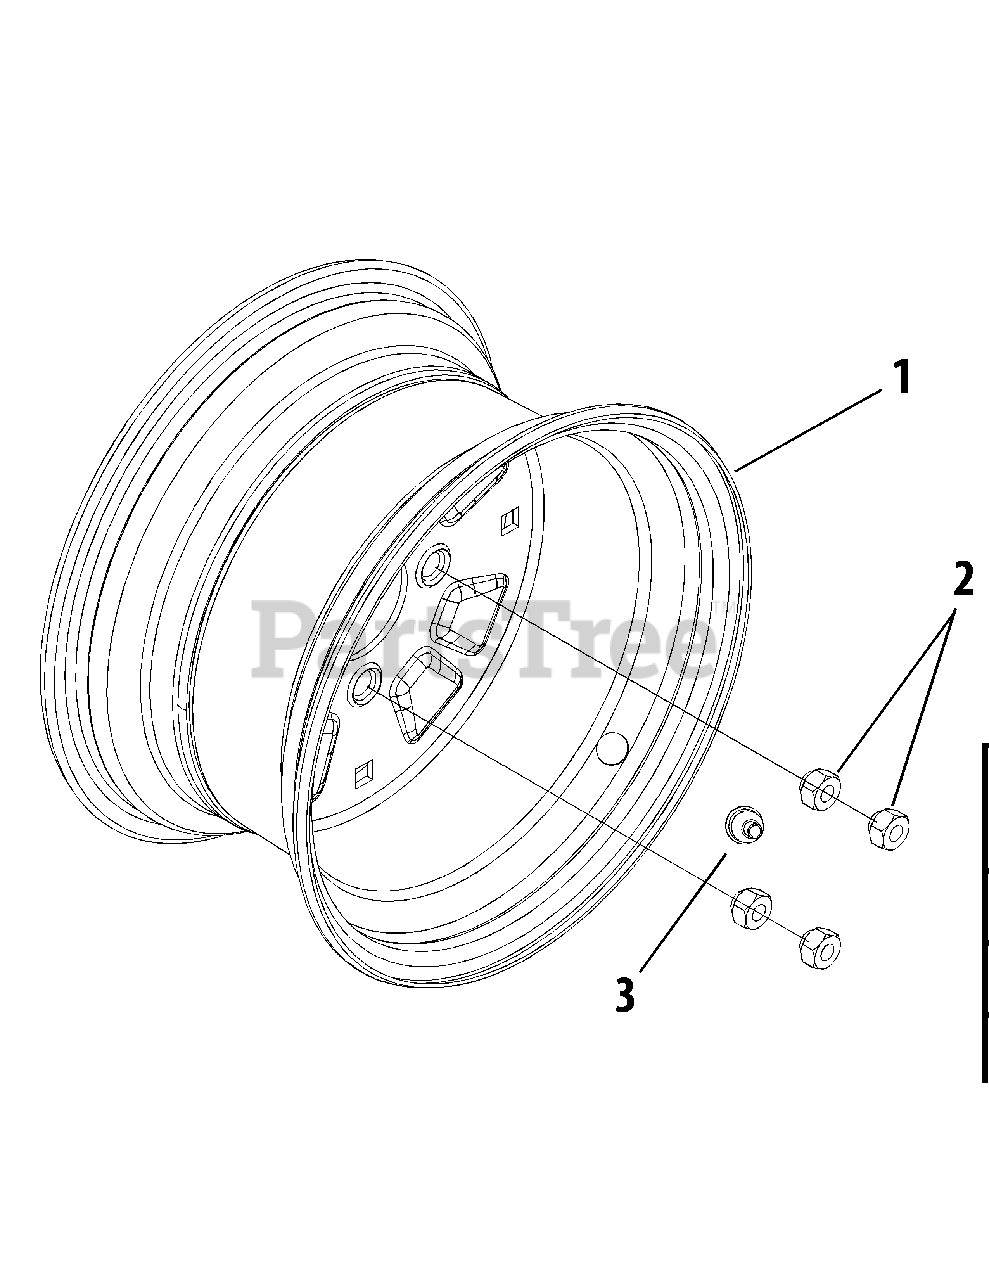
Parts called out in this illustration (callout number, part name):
1	Rim Assy, Rear
2	Nut, Lug, 7/16-14
3	Valve, Tubeless Air
